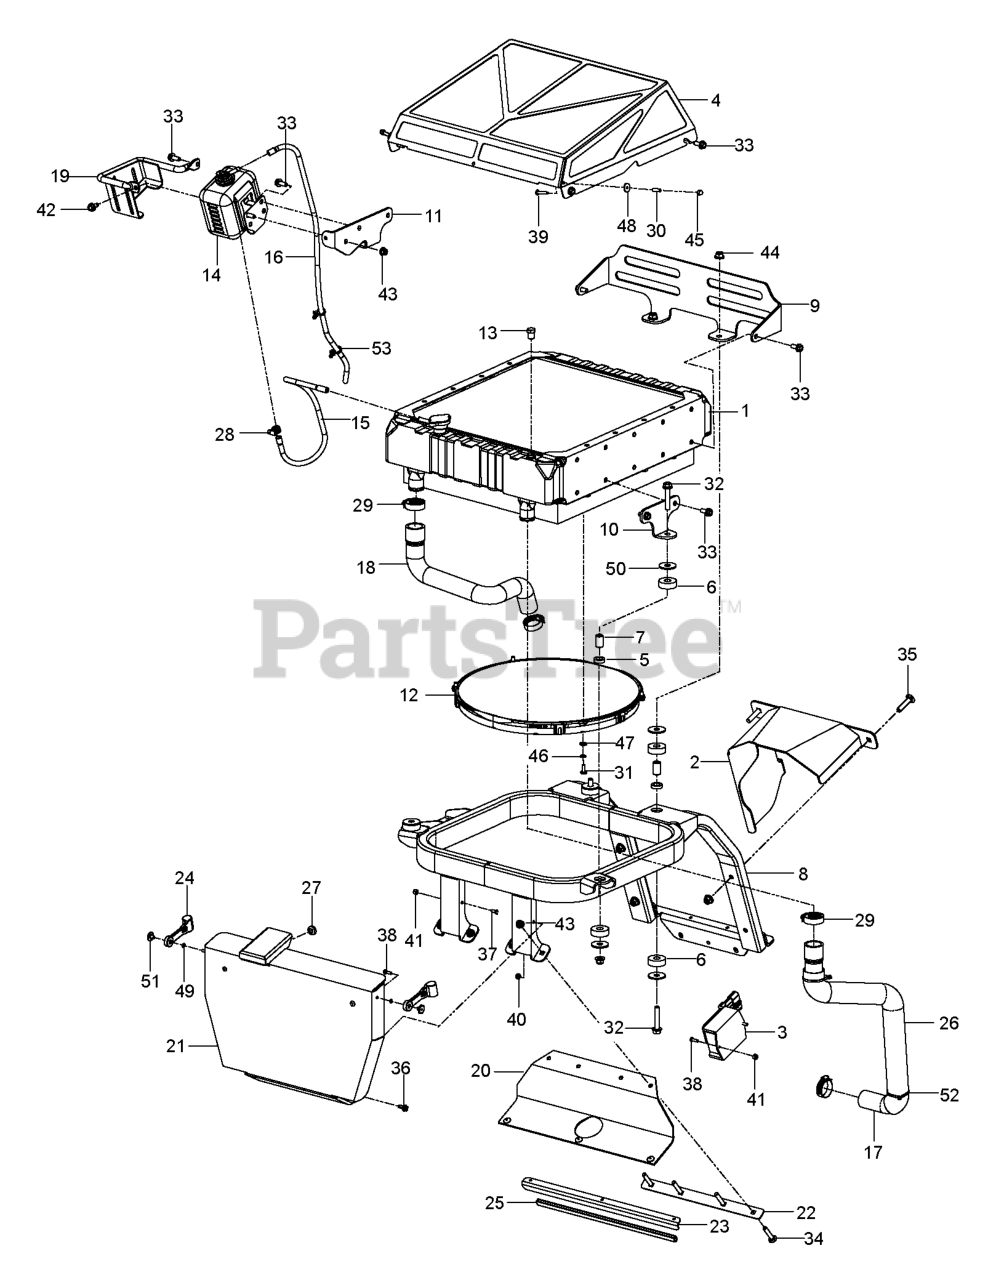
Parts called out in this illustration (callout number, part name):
2	SHIELD, BELT W/DECAL - GR
3	MODULE, FAN REVERSE
4	SCREEN, DEBRIS, BLK
5	ISO-MOUNT INSERT
6	ISO-MOUNT BUSHING
7	ISO MT. BUSHING
8	MOUNT, RADIATOR, GRAY
9	MOUNT, RADIATOR, REAR-BLK
10	MOUNT.RADIATOR.FRONT.BLACK
11	MOUNT, RADIATOR, BLK
12	FAN, ELECTRIC
13	FITTING, PIPE, 1/4 NPT
14	BOTTLE, OVERFLOW
15	HOSE, OVERFLOW, UPPER
16	HOSE, OVERFLOW, LOWER
17	HOSE, RADIATOR, LT
18	HOSE, RADIATOR, RT
19	GUARD, OVERFLOW, BLK
20	GUARD, BELT
21	GUARD, HOSE W/DECALS
22	STRAP, GUARD
23	STRAP, BELT GUARD, BLK
24	HOOD LATCH
25	RP.FLEX TRIM, BLK-LENGTH 1 FT
26	SLEEVE, HOSE
27	GROMMET, BUMPER
28	CLAMP, WORM GEAR, NO. 4
30	BSHG .202X.75 LG SPLIT ZD SPEC
31	HCS 1/4C X 5/8
32	HHFS 3/8-16 X 2.0 GD 5
33	HHFS 5/16-18 X 3/4
34	RHSNB 5/16-18X1 3/4
35	RHSNB 3/8-16X1-3/4
36	SCREW.1/4-20X5/8
37	HCS #10-24 X 1/2
38	SCREW #10-24 X 5/8
39	SCREW #10-24 X 1-1/8 ZD SPEC
40	JAM NUT 1/4C (2 2 PW01)
41	NUT 10-24 NYLOC
42	BOLT 5/16-18 X 3/4
43	5/16-18 NYLOC FLANGE NUT
44	NUT 3/8-16 HEX FLG NYLOC ZD
45	NUT 10-24 ACORN ZD
46	LOCKWASHER 1/4"
47	WASHER 1/4 SAE
49	WASHER - 3/16 LOCK ZD
50	7/16 HD FLAT WASHER
51	NUT 10-24 WELD PLATED
52	TIE, PLASTIC
53	TIE WRAP, 8-3/8", W/CLIP
